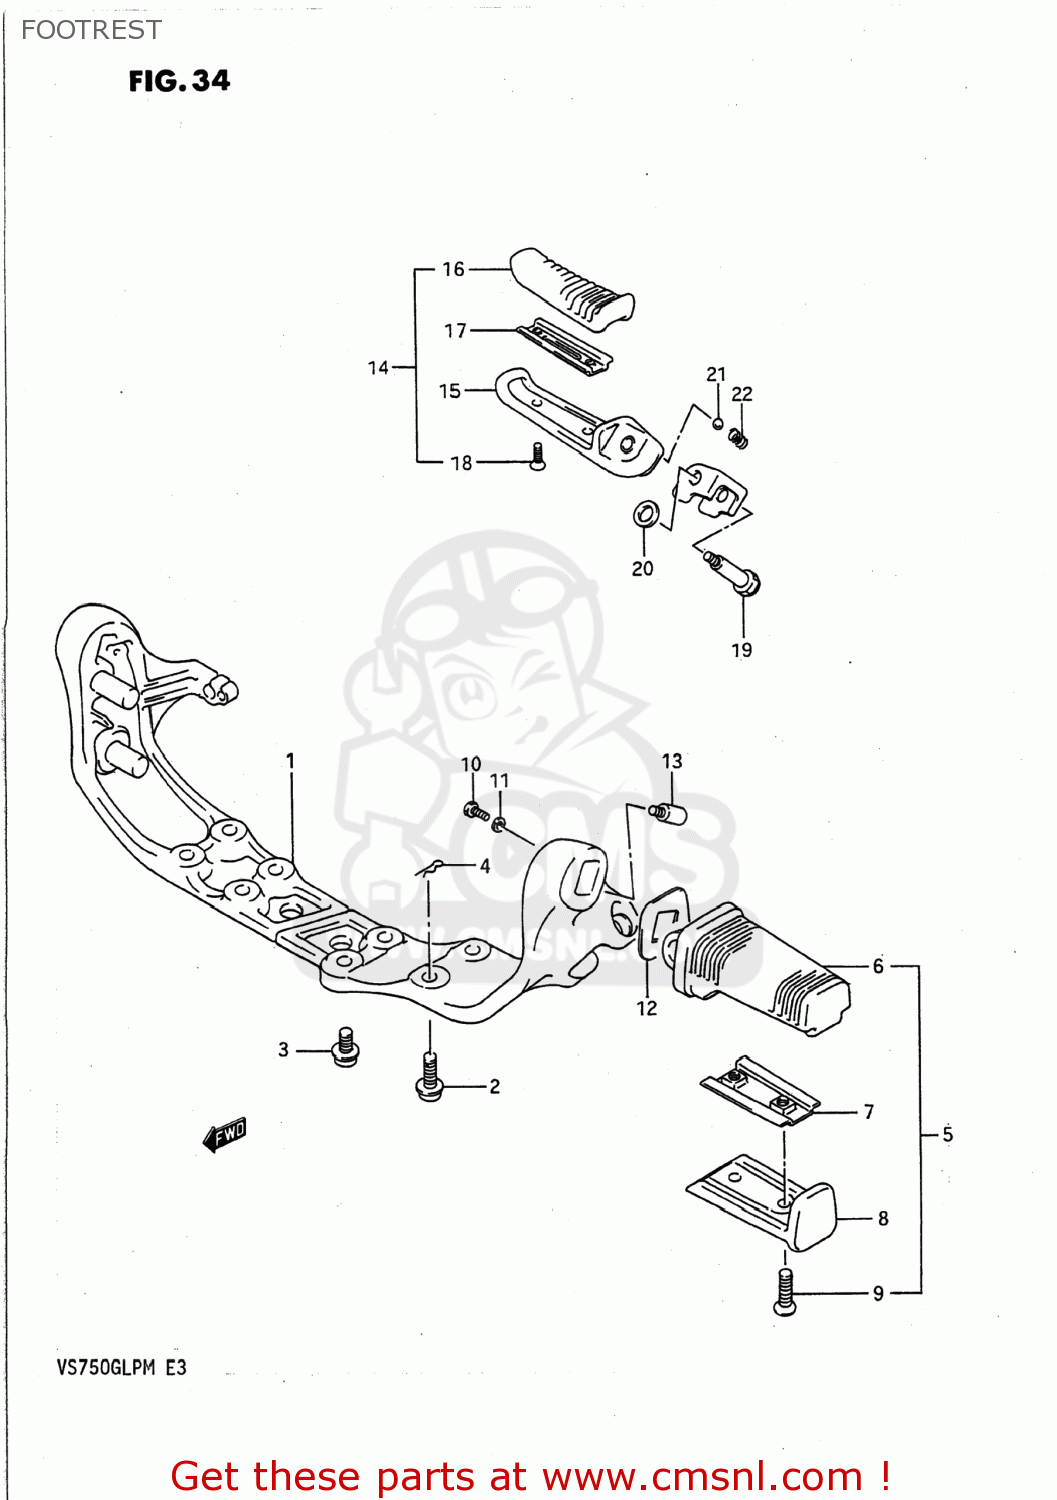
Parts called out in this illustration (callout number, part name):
1	BRACKET COMP,FRONT FOOTREST
2	BOLT(8X25)
3	BOLT
4	SNAP
5	FOOTREST ASSEMBLY,FRONT,LEFT
6	RUBBER,FR FOOTREST
7	PLATE,RUBBER STOPPER
8	COVER,FRONT FOOTREST
9	SCREW(5X20)
10	BOLT 5X12
11	LOCK WASHER
12	WASHER,FRONT FOOTREST
13	BOLT,FRONT FOOTREST
14	FOOTREST ASSY RH
15	BAR COMP,PILLION FOOTREST
16	RUBBER,PILLION FOOTREST
17	PLATE,RUBBER STOPPER
18	SCREW(5X16)
19	BOLT(6X34.5)
20	SHIM
21	BALL
22	SPRING
